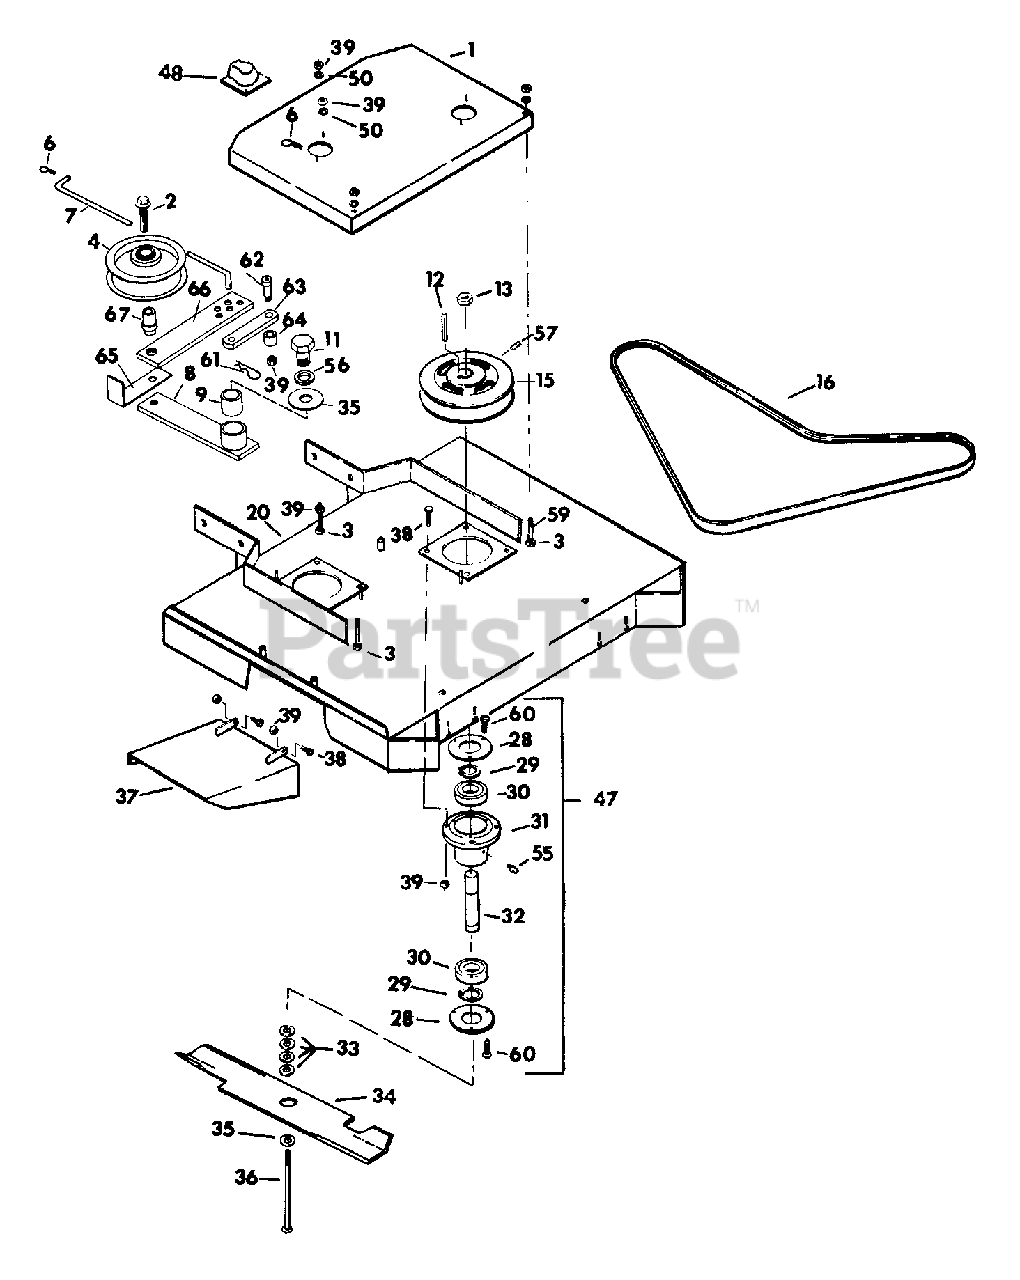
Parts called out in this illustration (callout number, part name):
1	Belt Shield w/Decal
2	3/8"-16x1-3/4" Whizlock Bolt
3	5/16"-18 Whizlock Nut
4	Heavy Duty Idler Pulley
6	#2 Hairpin Cotter
7	Lower Blade Drive Linkage
8	Idler Arm Assembly Complete w/Brg (P/N 76452)
9	Oilite Bearing
11	5/8"-11x1" Hex Hd. Cap Screw
12	1/4" Sq. x 1-1/4" Machine Key
13	5/8"-18 Regular Hex Nut
15	Pulley w/Set Screws (P/N 76956)
16	Belt
20	Front Deck w/Decals
28	Cutter Housing Cap
29	Snap Ring
30	Cutter Housing Bearing
31	Cutter Housing
32	Cutter Spindle
33	Blade Spacers
34	(.164") Ultra High Lift Blade-16" Long
34	BLADE, 16-1/4" (.250" Ultra High Lift)
35	5/8" SAE Washer
36	5/8"-18x7-1/2" Hex Hd. Cap Screw-Grade 5
37	Chute Assembly
38	5/16"-18x1" Hex Hd. Cap Screw
39	5/16"-18 Nyloc Hex Nut
47	Complete Cutter Housing Assembly
48	Shaft Guard
50	5/16" Std. Flat Washer
55	1/8" NPT Straight Zerk
56	5/8" Lock Washer
57	5/16"-18x3/8" Nyloc Knurled Cup Point Set Screw
59	5/16"-18x3-1/4" Hex Hd. Tap Bolt-Grade 5
60	#10-24x3/8" Pan Hd. Slt. Mach. Screw
61	#4 Hairpin Cotter
62	3/8"x3/4" Knurled Socket Hd. Shoulder Bolt
63	Assist Arm
65	Belt Snubber
66	Tightening Arm
67	Engagement Flange Bushing
